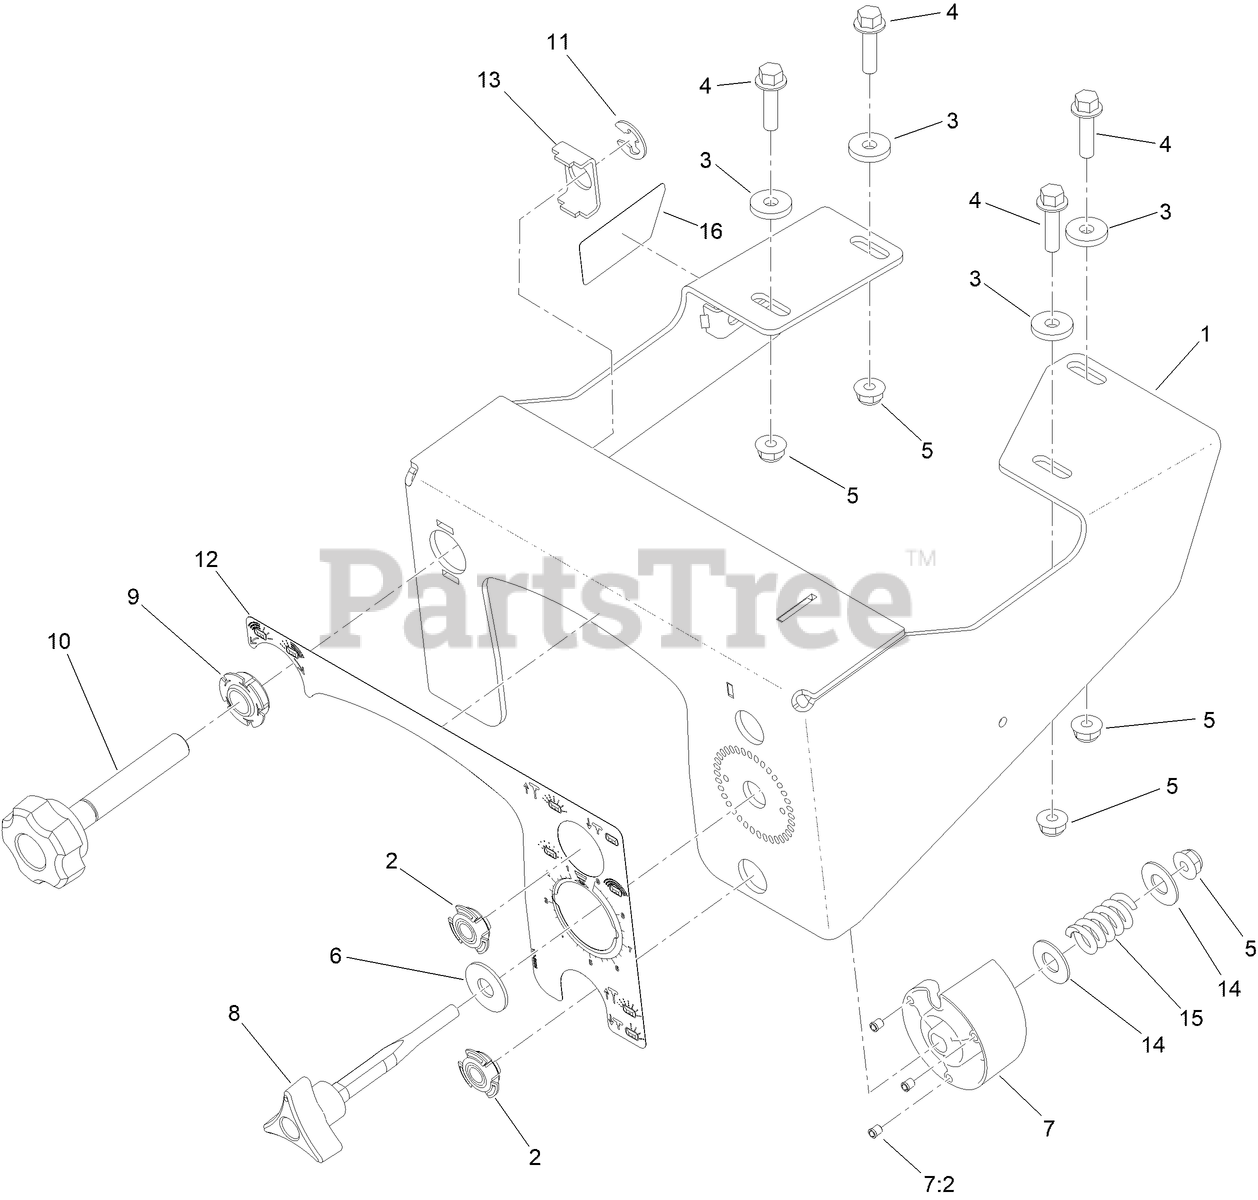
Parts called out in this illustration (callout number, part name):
1	CONSOLE-HOPPER
2	BEARING-SPHERICAL
4	SCREW-HHF
5	Nut-Hex Flange
7	DIAL-RATE
7:2	PLUNGER-SPRING, BALL
8	KNOB-RATE
9	BEARING-SPHERICAL
10	KNOB-DIFFUSER
12	DECAL-HOPPER
13	STOP-DIFFUSER
14	WASHER,FLAT,3/8ST/ST 18-8
15	SPRING-COMPRESSION
16	DECAL-PATTERN INDICATOR
